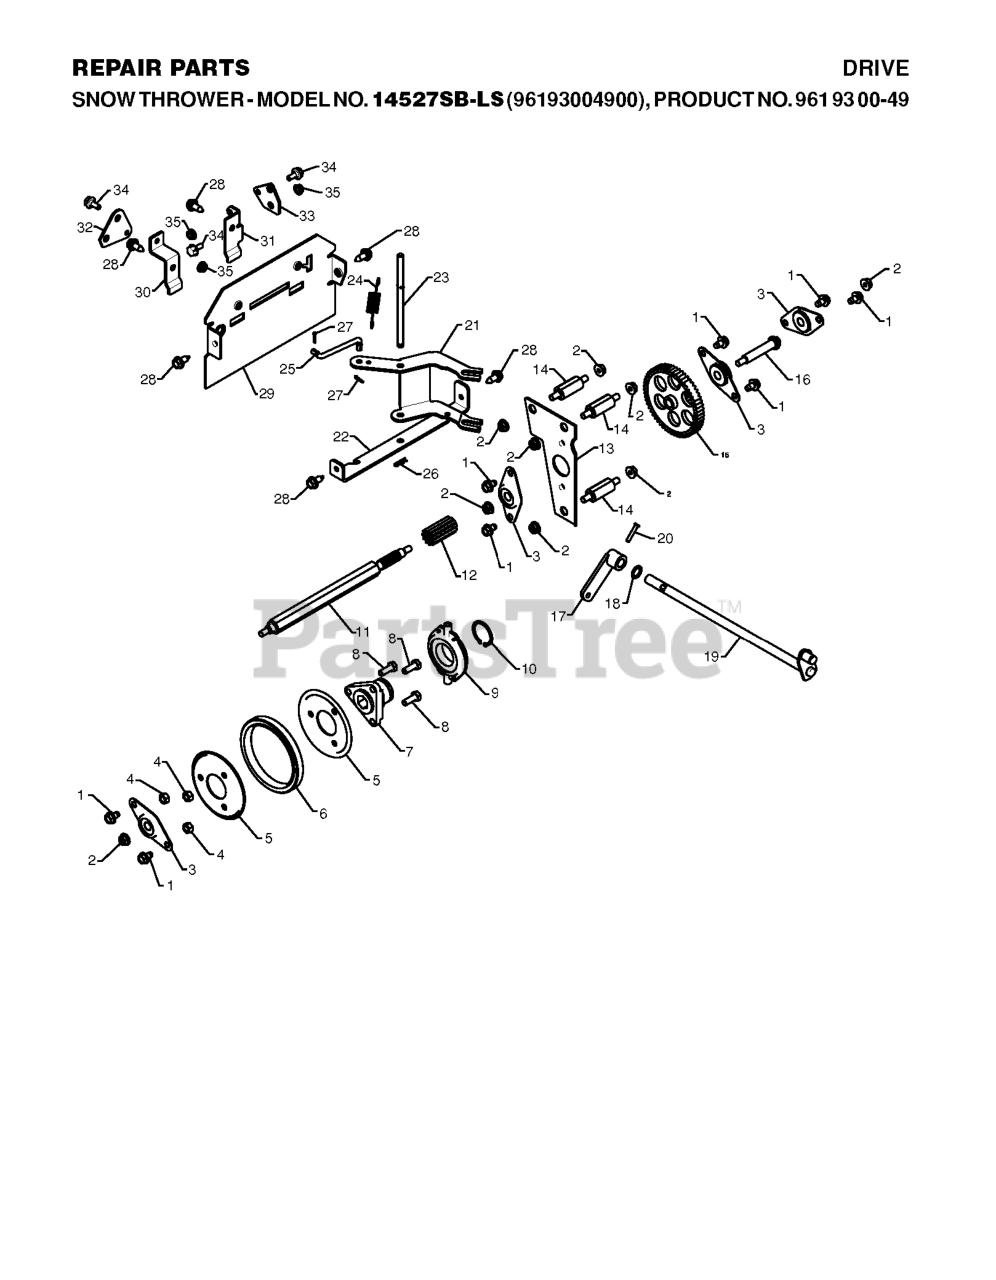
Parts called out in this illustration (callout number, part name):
1	Screw 5/16-18 x 1/2 Hex, Self Tapping 5/16-18 x 1/2
2	NUT.LOCK.5/16-18
3	BEARING, FLANGE
4	NUT.CENTERLOCK.5/16-
5	PLATE.RUBBER.WHEEL
6	RING, RUBBER WHEEL
7	HUB, RUBBER WHEEL
8	BOLT
9	TRUNNION BEARING ASSY
10	RETAINING RING (2 2)(3 2)
11	SHAFT.HEX.LONG
12	GEAR, PINION
13	AUXILLARY PLATE
14	SPACER, PLATE
15	GEAR, INTERMEDIATE
16	SHAFT, AUXILIARY
17	ARM, AUGER CONTROL
18	THRUST WASHER
19	CONTROL.SHAFT.ASM
20	CLEVIS PIN
21	LEVER, SPEED CONTROL
22	BRACKET, PIVOT, SHIFT
23	PIN, PIVOT
24	SPRING, BIAS
25	LINK, SPEED CONTROL
26	RETAINER CLIP PM
27	RETAINER CLIP
28	BOLT.HEX.HD.WASHER.5/16-18X.75
29	PLATE.REAR.SNOW.PNT.ORANGE
30	BRACKET.SHIFTER.PLATE.BZP
31	BRACKET.CLUTCH.PLATE.BZP
32	PLATE.SHIFTER.BZP
33	PLATE.CLUTCH.BZP
34	BOLT.SHOULDER.3/X.25
35	NUT.HEX.FLANGE.1/4
